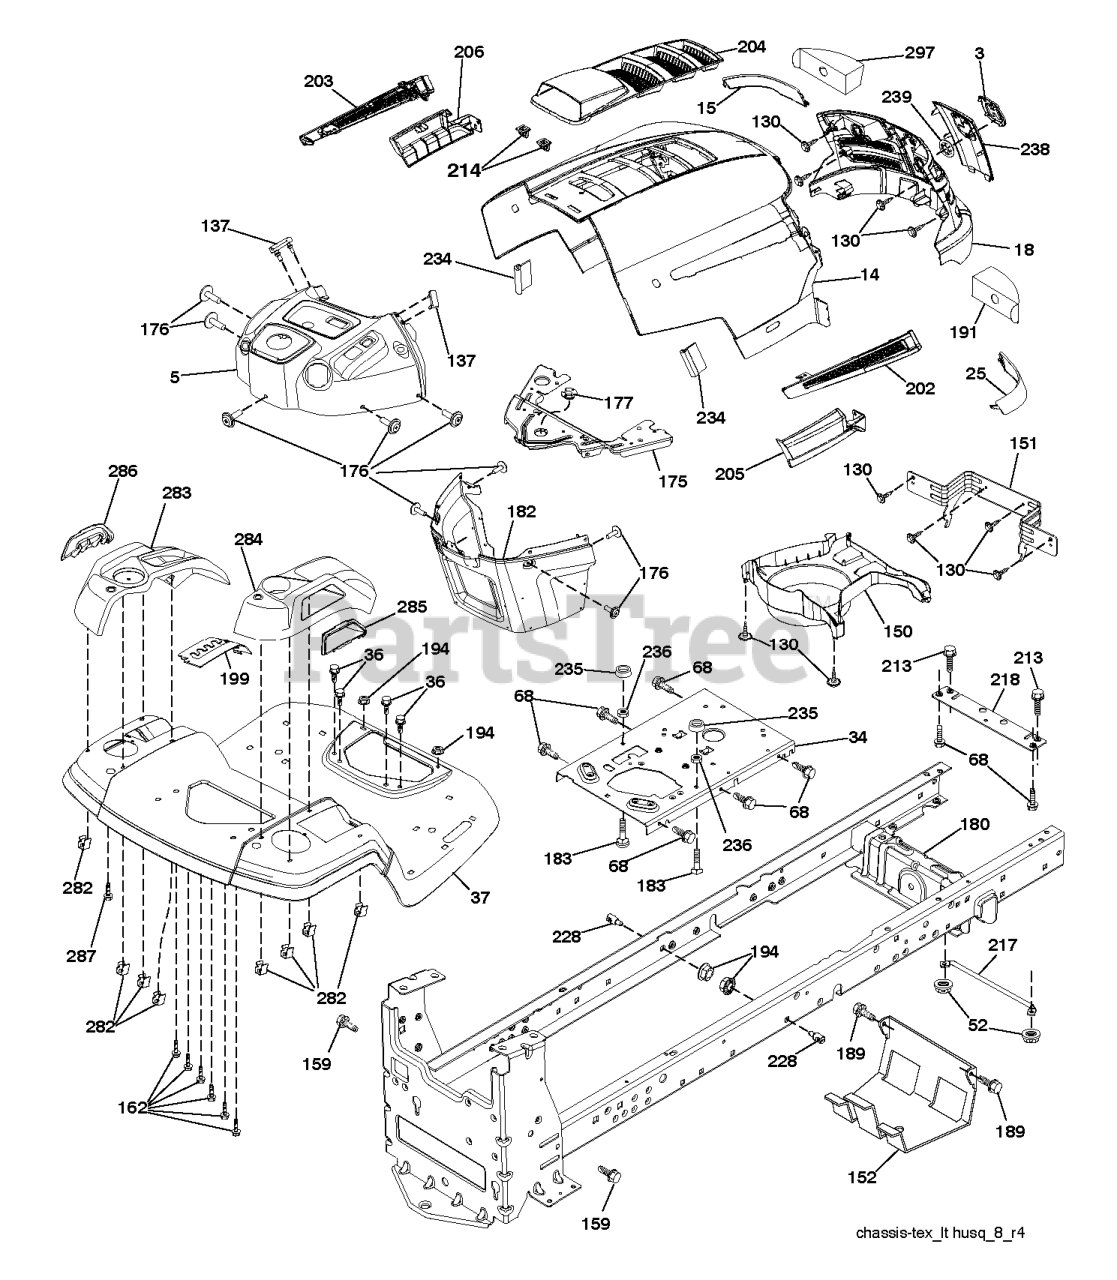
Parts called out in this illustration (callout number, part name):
1	TUBE HANDLE
2	Bolt Carriage 1/4-20 x 2.0 Gr.5
3	NUT T
4	HANDLE.BAGGER.W/LVRS.BLK.CRD
5	SCREW.PAN.HEAD
6	REPL BY 532 75 00-29
8	COVER.PNT.BGR.CRD.WSLOTS.MS668
9	Bolt Carriage 1/4-20 x 2.25d x Gr.5
10	TUBE
11	BRACKET.SUPPORT.UPPER.BAG.CRD
12	BRKT PIVOT
14	BOLT-HEX EAK
15	RETAINER-SPRNG RB
16	NUT LOCK FLG 3/8-16 UNC
17	RP BOLT 5/16-18 X3/4 ZN/YEL GR
18	WASHER M
19	NUT LOCK HEX FLANGE 5/16-18
20	BRKT.PIVOT.RH.CRD
21	GRASS BAG
22	BRKT.SIDE.BAG.CRD
23	TUBE.UPPER.BAG.CRD
24	TUBE.PIVOT.BAG.CRD.BLACK
26	TUBE.LOWER.BAG.CRD
28	GRIP.HANDLE.BLACK
31	RETAINER CLIP
32	RIVET,DRILLED
33	PLUG.MULCHER.92 CRD
34	HANDLE.MULCHER.92.CRD (2 2)
36	WASHER
37	Plug Support Bagger CRD
38	BOLT.5/16-18X2.5
39	SEAL.TRIM.37'
41	BRKT.VERT.ADJ.BAGGER.CRD
43	PLUG, TUBING END
